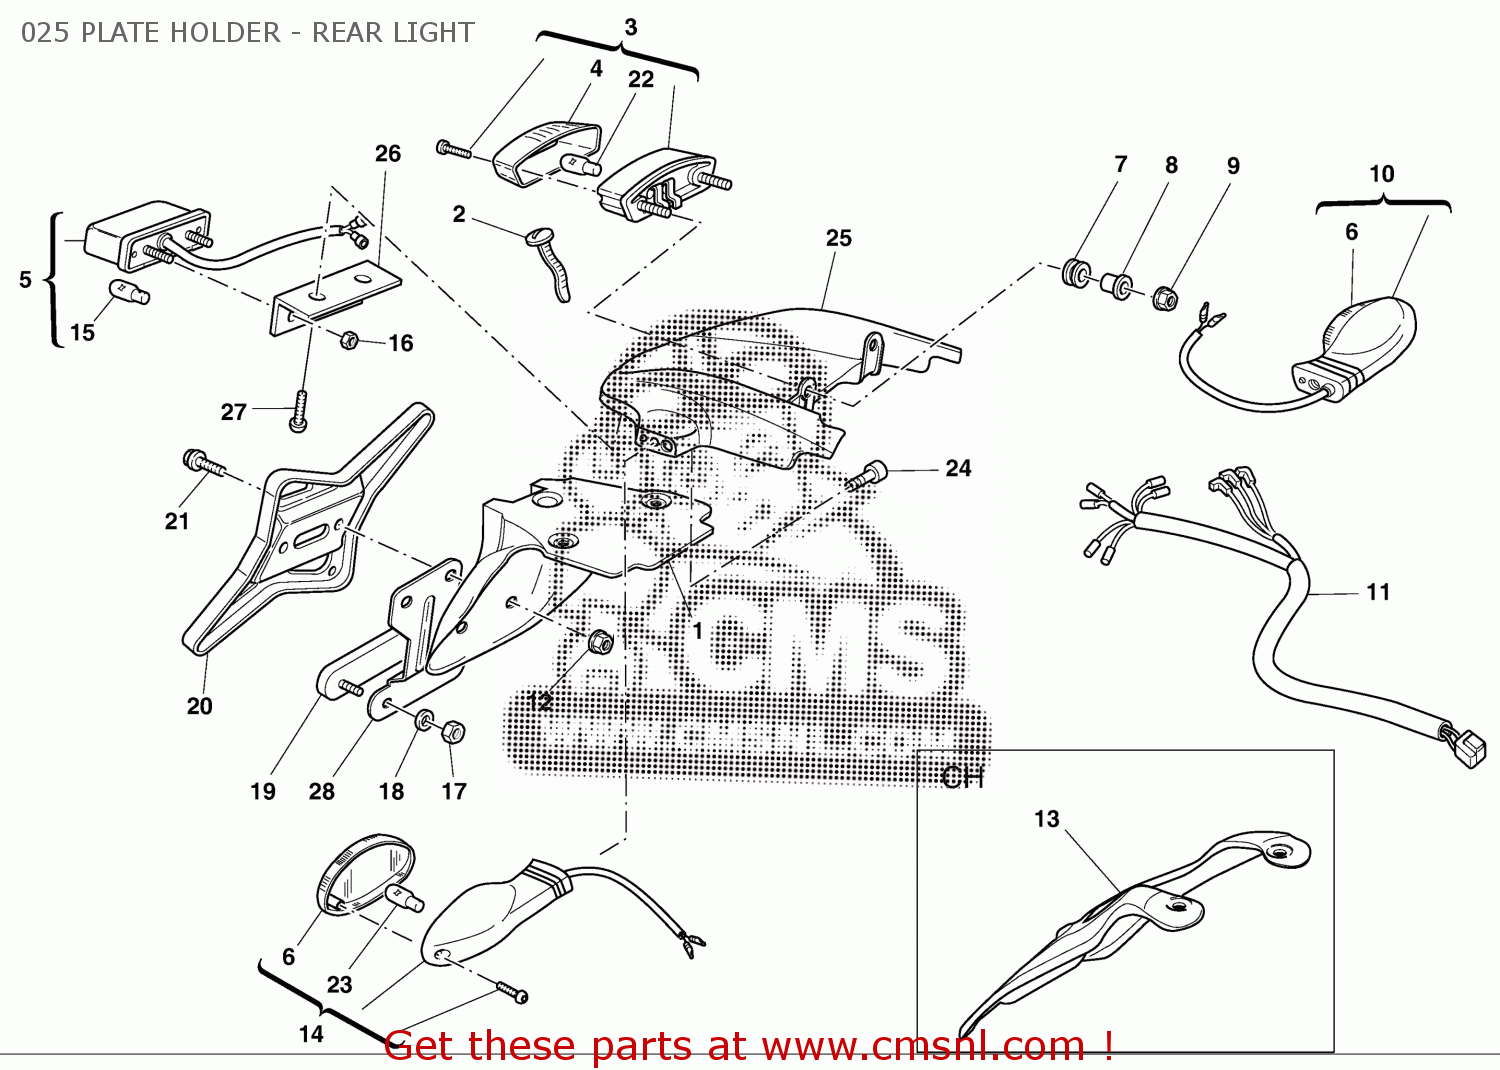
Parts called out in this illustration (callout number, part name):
1	PLATE HOLDER
2	CLAMP
3	TAILLIGHT
4	LENS, TAILLIGHT
5	LAMP, LICENSE PLATE
6	LENS FLASHER LIGHT
7	VIBRATION DAMPER PAD
8	SPACER 8X6.2X8.5
9	SELF LOCKING NUT M6 H5.5
10	REAR FLASHER LIGHT,LEFT
11	CABLE, TAILLIGHT
12	NUT, FLANGED M6X1.00
13	MUDFLAP
14	REAR FLASHER LIGHT, RIGHT
15	WEDGE BASE BULB 12V5W
16	NUT 6MM
17	NUT
18	WASHER
19	REFLEX REFLECTOR, REAR
20	NUMBER PLATE HOLDER
21	SCREW TEF M6X22
22	LAMP 12V 5/21W
23	BULB 12V 10W BA15S
24	SCREW TCEI M6X1.00X16
25	PROTECTION
26	BRACKET, TAILLIGHT
27	SCREW
28	BRACKET, REFLECTOR
